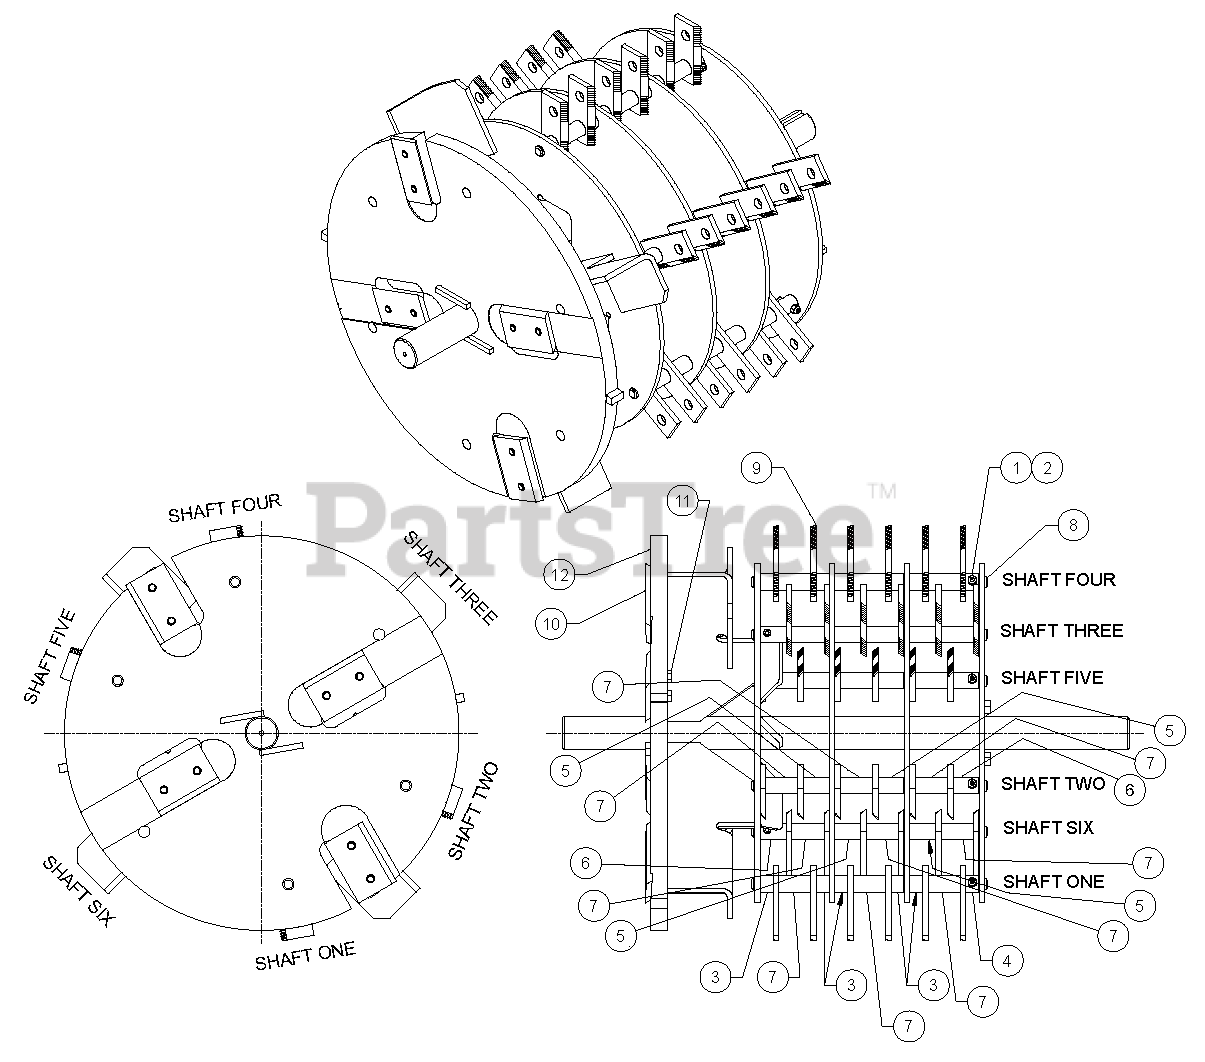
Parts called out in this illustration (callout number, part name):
1	NUT, #10 X 24 NYLOCK
2	SCREW, 10-24 X 1-1/8"
3	SHORT SPACER .75 X .59 (LARGE C/S)
4	SHORT SPACER .75 X .59 W/HOLE (LARGE C/S)
5	SPACER, .75 X 1.18
6	MEDIUM SPACER-BORED .75 X 1.18 W/HOLE (LARGE C/S)
7	LONG SPACER .75 X 1.47 (LARGE C/S)
8	ROTOR KNIFE SHAFT (LARGE C/S)
9	SHREDDING KNIFE, RECTANGULAR
10	BLADE, TWO EDGE CHIPPER
11	BOLT, 5/16" X 1" HEX HD.
12	5 INCH C/S ROTOR WELDMENT
